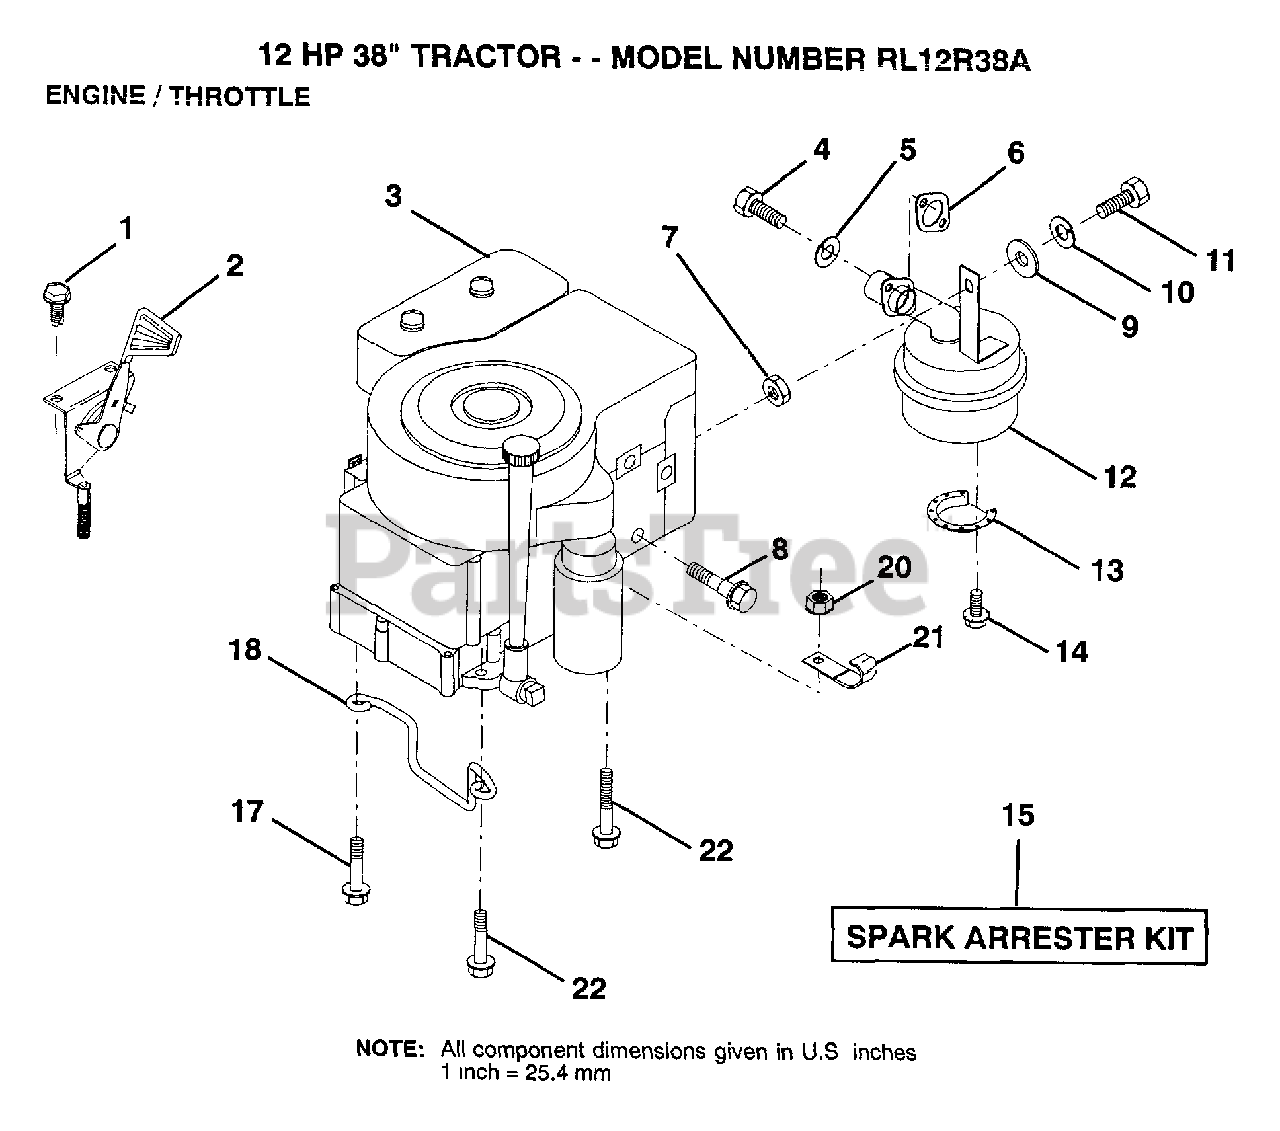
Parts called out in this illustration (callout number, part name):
1	SCREW
2	THROTTLE CONTROL
3	ENGINE BRIGGS AND STRATTON
4	SCREW
5	LOCKWASHER
7	NUT.HEX.5/16-18
8	BOLT T
10	LOCKWASHER
12	MUFFLER
13	DEFLECTOR.222573
17	SCREW LT
18	"KEEPER,DR BELT GR"
20	NUT
21	CLIP T
22	SCREW LT
